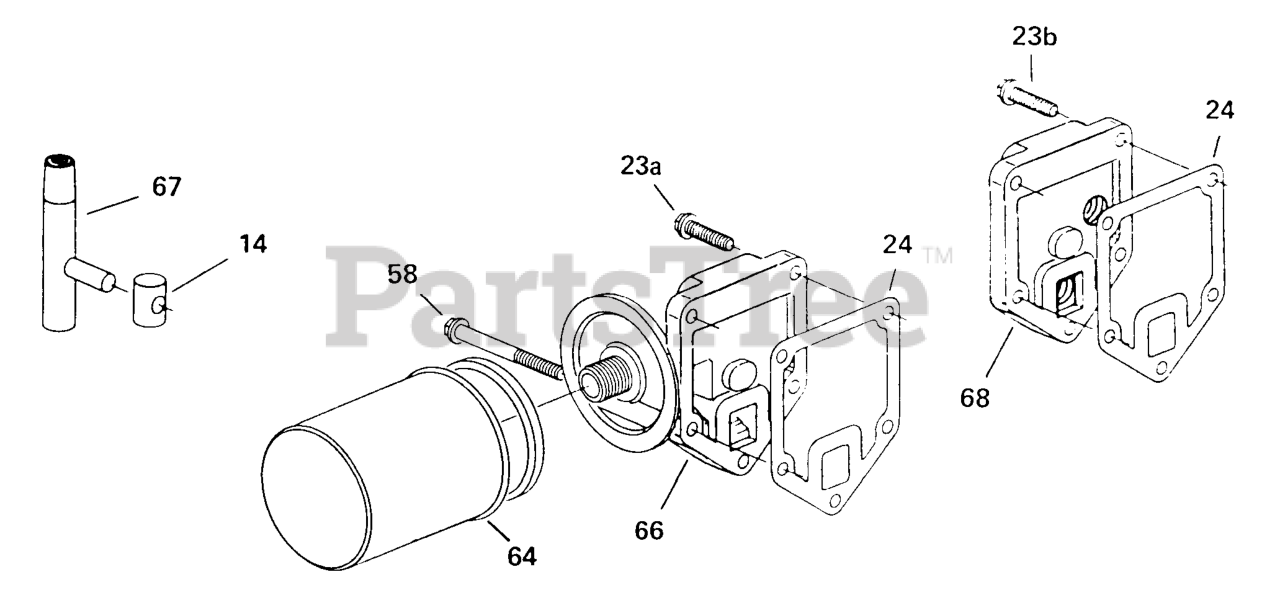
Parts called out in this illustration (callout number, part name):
23A	Screw, 1/4-20 Hex Flange
23B	Screw, 1/4-20 Hex Flange
64	Filter, (W/Seal)
